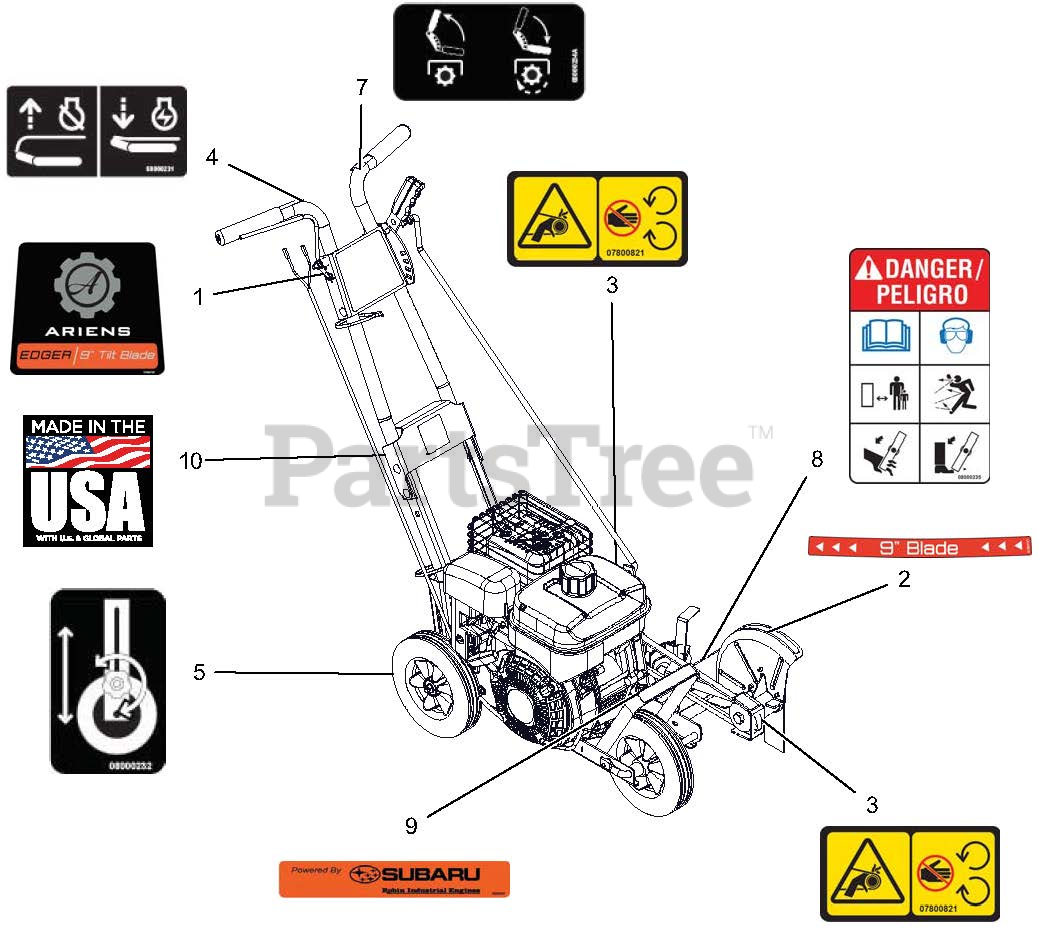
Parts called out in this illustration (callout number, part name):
1	DECAL-ARIENS EDGER
2	DECAL-9" BLADE
3	DECAL-SAFETY-GUARDING
4	DECAL, EDGER OPC
5	DECAL, EDGER DROP WHEEL
7	DECAL, EDGER DEPTH CONTROL
8	DECAL, EDGER WARNING
9	DECAL, SUBARU
10	DECAL, MADE IN USA
